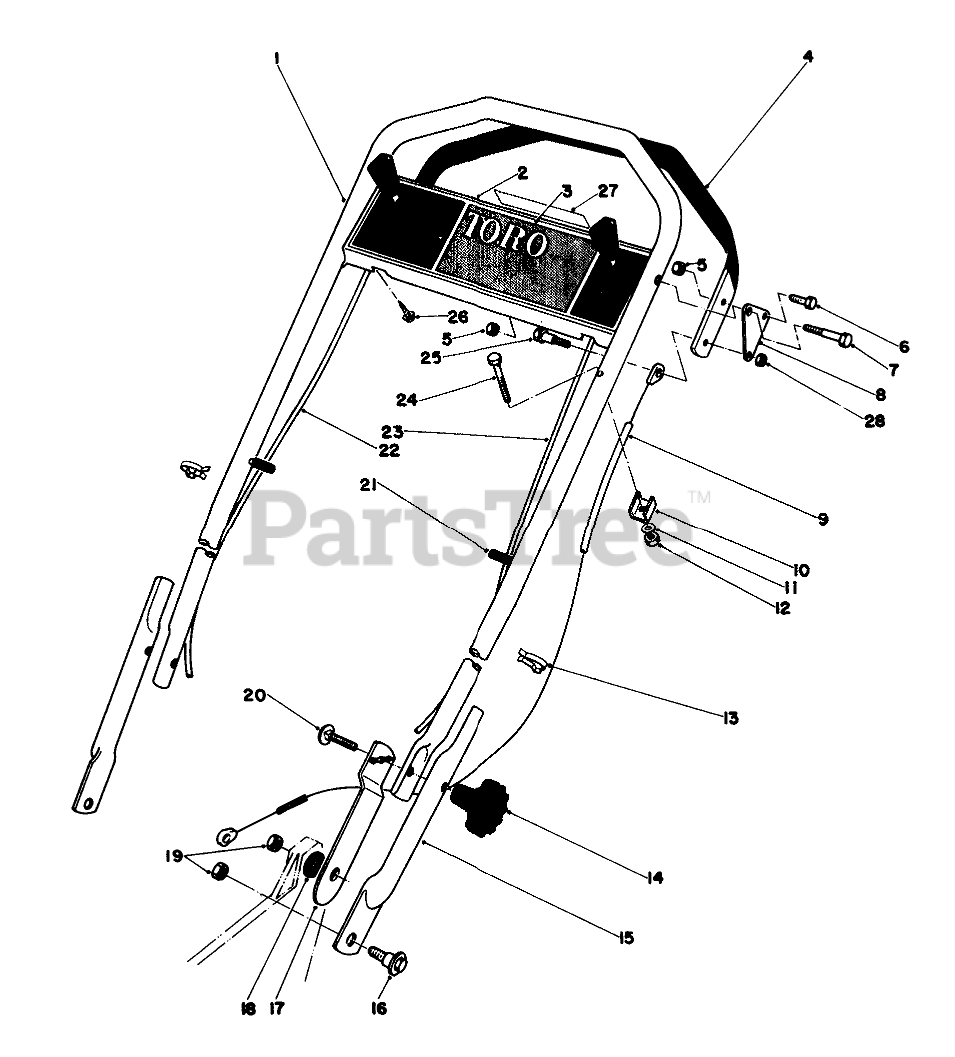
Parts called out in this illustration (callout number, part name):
1	Upper Handle
2	Control Plate
3	Decal-Control Panel
4	Demand Handle
6	SCREW-HH
7	BOLT-SHOULDER
8	Bracket-Demand
9	DEMAND HAND CABLE
10	CLAMP-CABLE
11	WASHER-FLAT
15	LOWER HANDLE
16	SCREW-SHOULDER
17	Handle Latch L.H.
18	SPACER
19	Nut
20	SCREW-CARR
21	Cap Vinyl
22	Ground Speed Control
23	Throttle Control
24	SCREW-HH
25	SHOULDER BOLT
26	SCREW-HWHTF
27	Decal-Select-a-Pace
28	NUT-HEX, SIDE DEFORM
